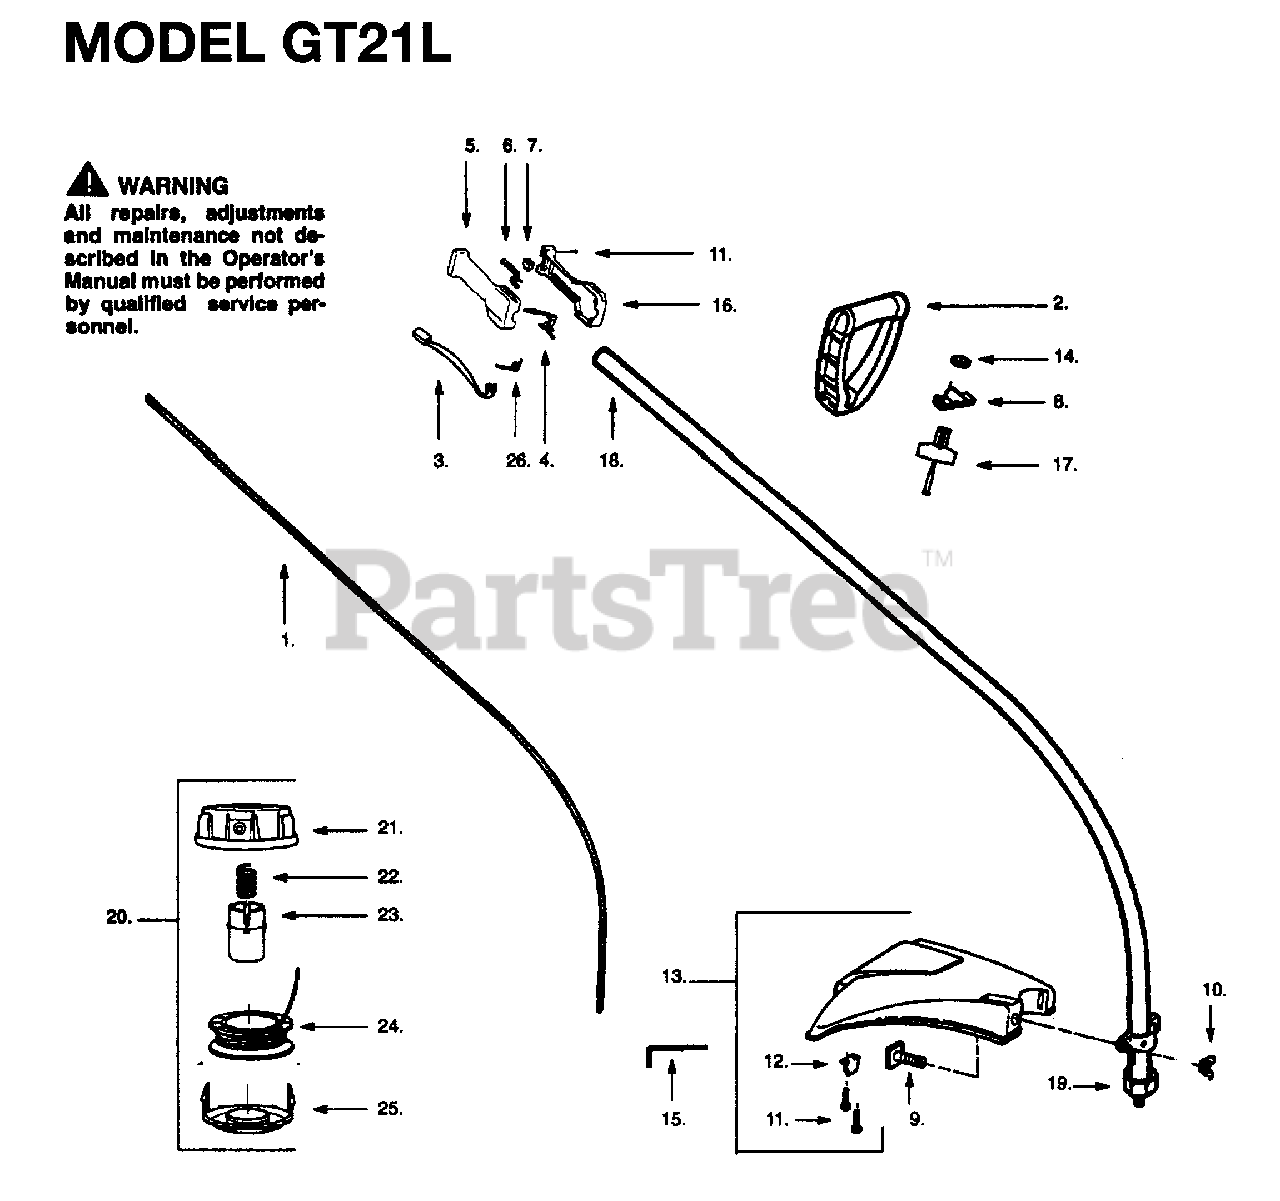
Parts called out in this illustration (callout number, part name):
2	"D" HANDLE
4	THROTTLE TRIGGER
8	CLAMP-ASSIST HANDLE
9	BOLT, TYPE 2
10	WING NUT
11	SCREW-10-14 X 13/16 (PL
12	LINE LIMITER
14	NUT (1/4-20)
15	HEX WRENCH 5/32
17	KIT "T" HANDLE
18	DRIVE SHAFT
20	CUTTING HEAD ASSEMBLY
21	HUB AND SHAFT ASSY
24	SPOOL W/ LINE NLA
26	SPRING-LEVER RETURN
